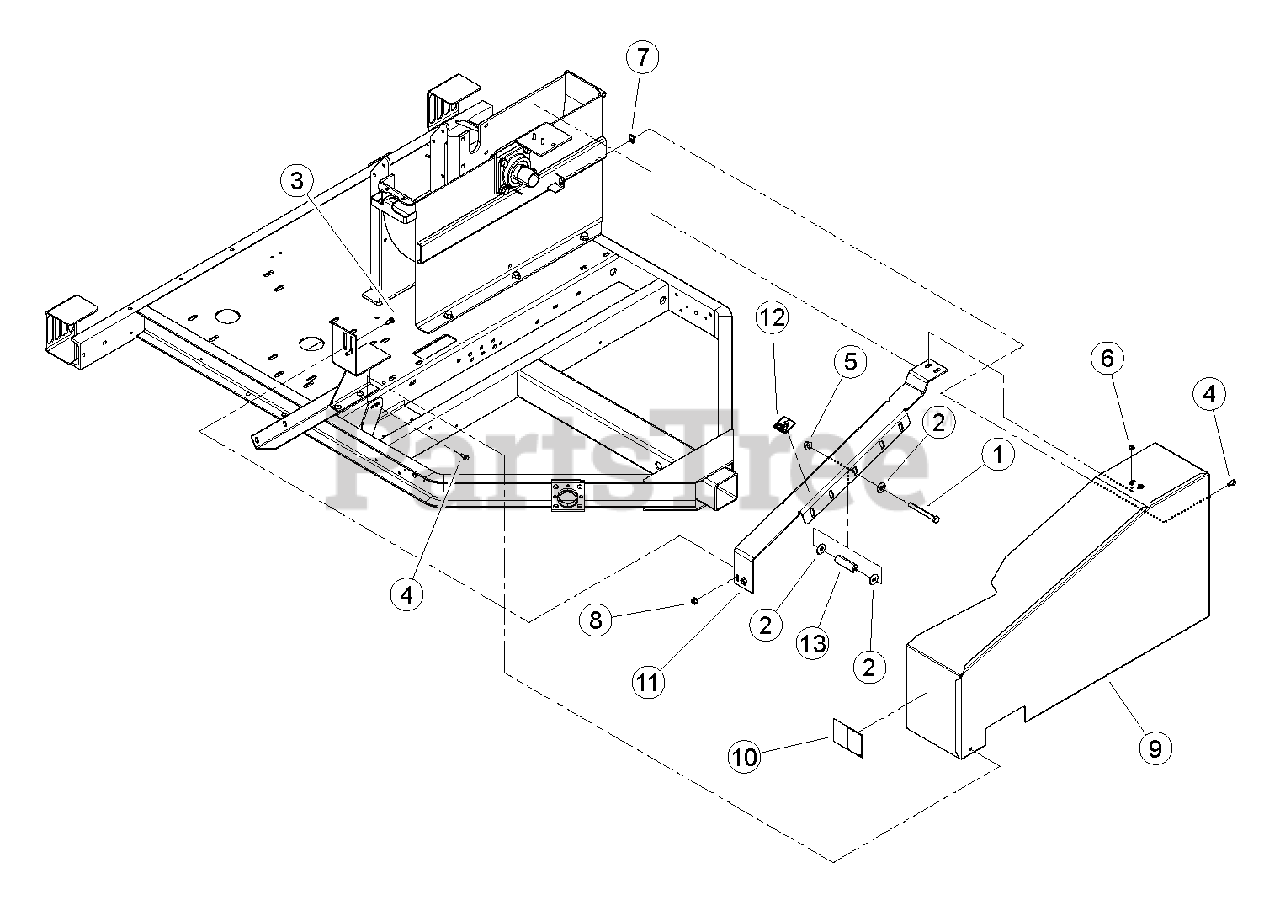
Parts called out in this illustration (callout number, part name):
1	BOLT, 1/2 X 4-1/2" GR5 HHCS NC ZP
2	WASHER, 1/2" FLAT ZP
3	BOLT, 3/8 X 1" GR5 CRG NC ZP
4	BOLT, 5/16 X 3/4 FLANGE NC
5	NUT, 1/2-13 NYLOCK FLANGE
6	NUT, 5/16 SERRATED FLANGE NC ZP
7	NUT, 5/16"-18 TINNERMAN U-TYPE
8	NUT, 3/8-16 NYLOCK FLANGE
9	ASSEMBLY, BELT SHIELD W/ DECALS
10	DECAL, CLUTCH ENGAGEMENT ISO
11	ASSEMBLY, BELT GUIDE W/ DECALS
12	DECAL, SHIELD DANGER ISO
13	SPACER, TUBE 1 OD X .5 ID X 3.13
